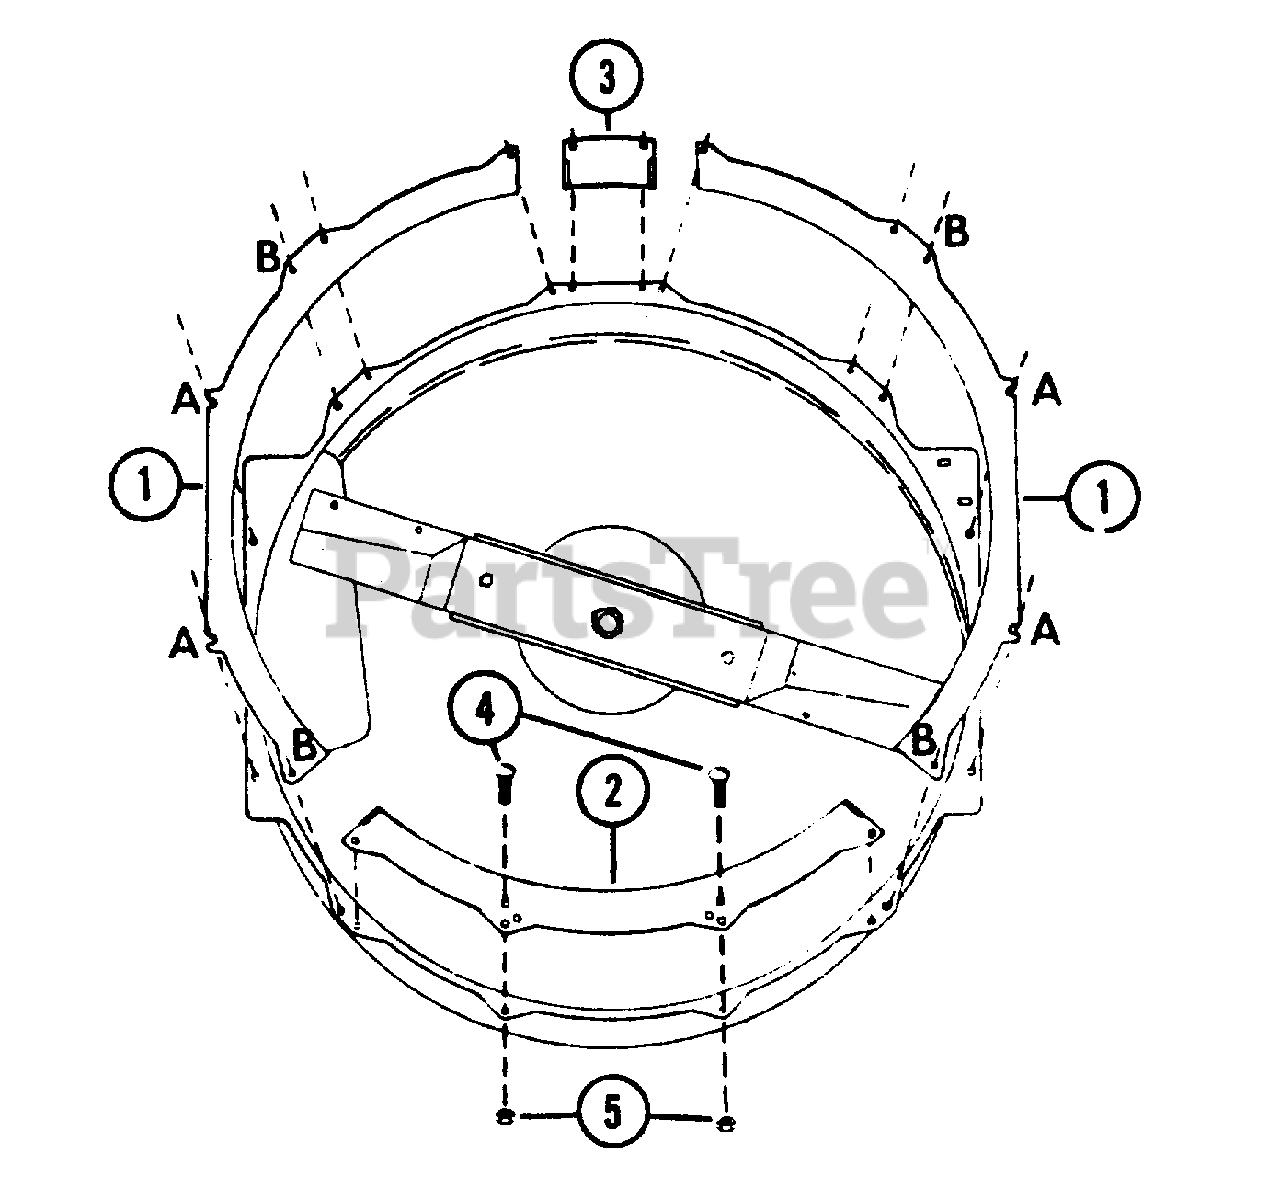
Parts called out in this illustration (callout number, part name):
1	FLANGE, SIDE
2	FLANGE, BACK
3	FLANGE, FRONT
4	BOLT, 1/4-20X.625 RD HD SQ NK
5	NUT, LOCK 1/4-20
